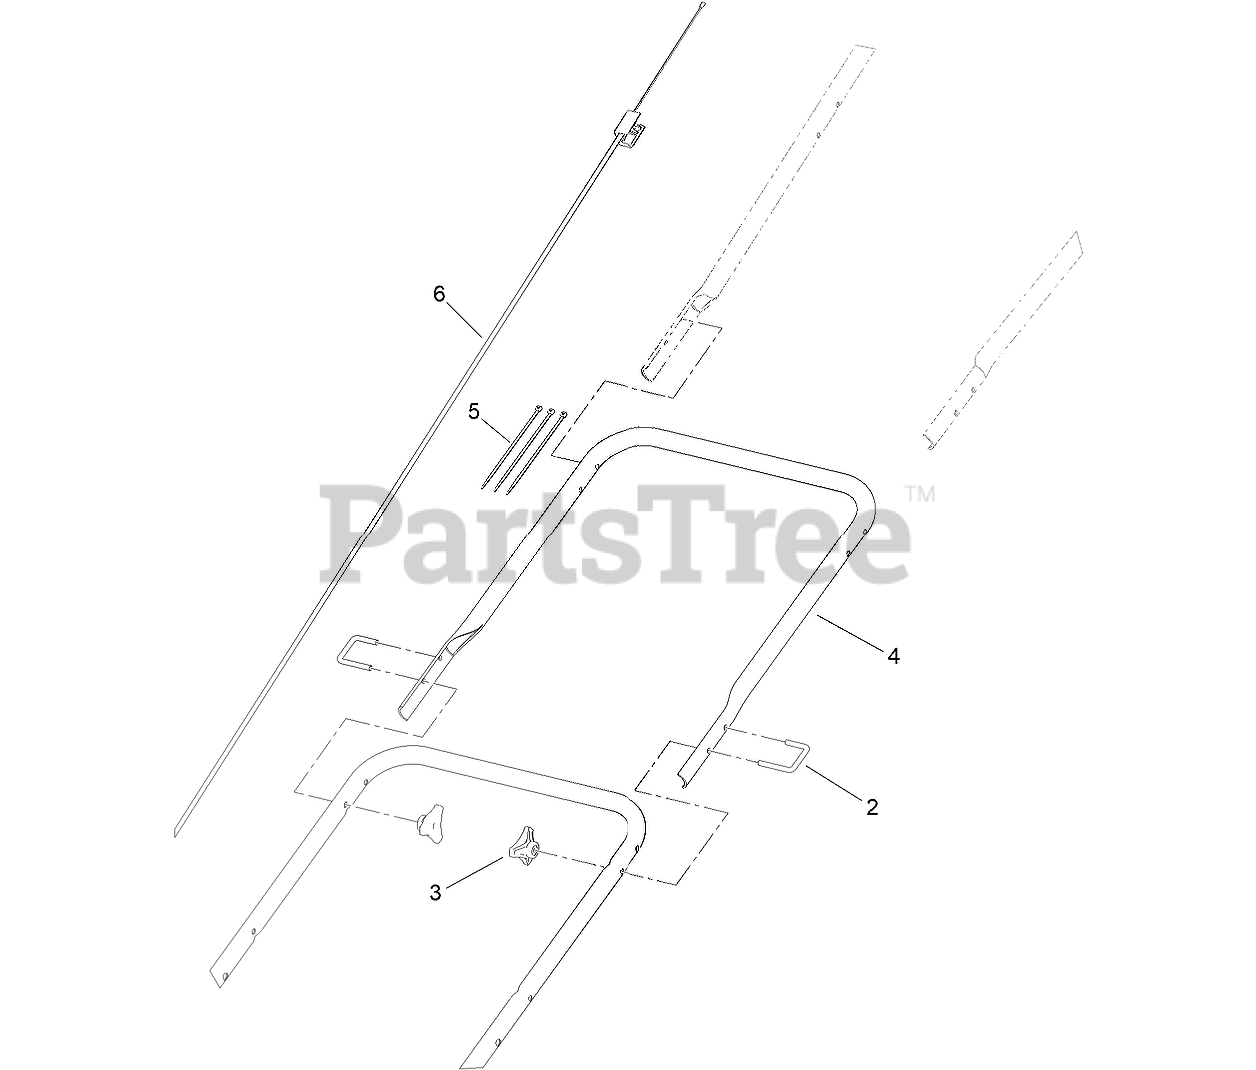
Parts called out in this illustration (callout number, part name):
2	BOLT-U
3	HANDWHEEL
4	EXTENSION-HANDLE
5	TIE-CABLE
6	OPC CABLE
